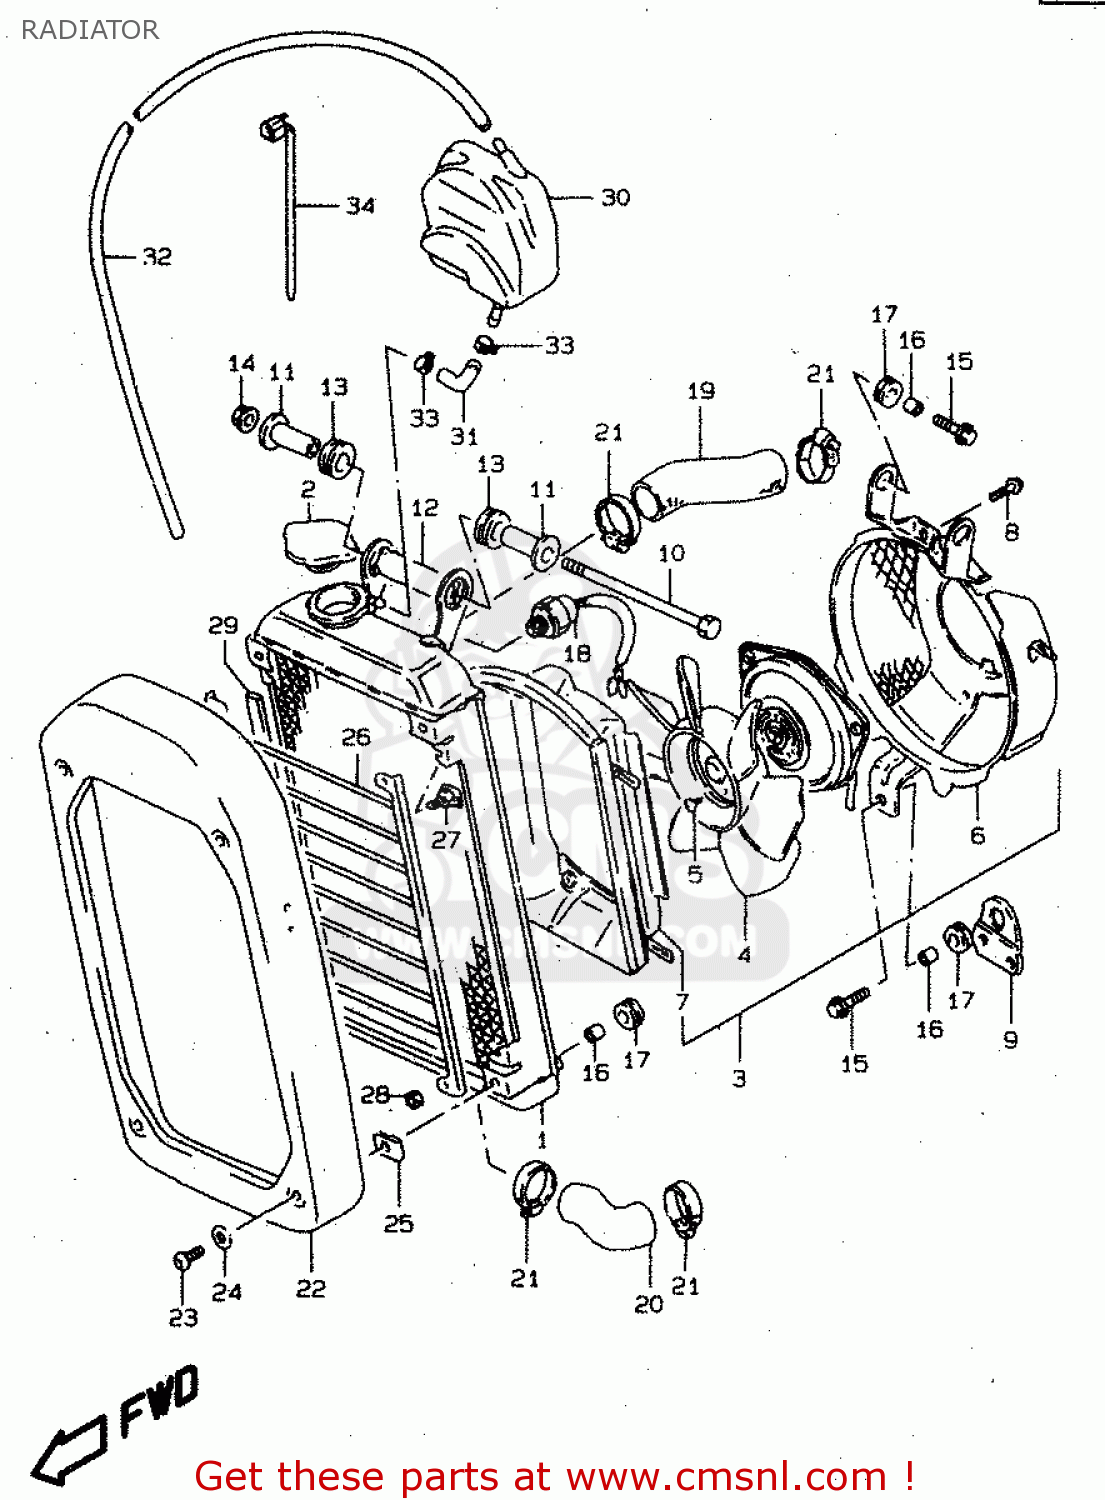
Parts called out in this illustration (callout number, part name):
1	RADIATOR ASSY,WATER
2	CAP,RADIATOR
3	FAN ASSY,RADIATOR
4	FAN
5	SCREW 4X6
6	SHROUD,FAN
7	DUCT,FAN
8	SCREW
9	BRACKET,RADIATOR FAN
10	BOLT(10X135)
11	SPACER,RADIATOR CUSHION NO.2
12	SPACER,RDTR CUSH NO.2 OUTER
13	CUSHION
14	NUT
15	BOLT
16	SPACER(6.5X9X8)
17	CUSHION
18	SWITCH,RADIATOR FAN
19	HOSE,RADIATOR INLET
20	HOSE,WATER PUMP OUTLET
21	CLAMP
22	COVER,RADIATOR
23	SCREW(6X10)
24	WASHER(6.5X14X2)
25	NUT
26	BUMPER,RADIATOR
27	BOLT
28	NUT
29	CUSHION,RADIATOR BUMPER
30	TANK,RESERVOIR
31	HOSE,RESERVE TANK INLET
32	HOSE,RESERVOIR TANK OUTLET
33	CLIP
34	CLAMP(L:125)
